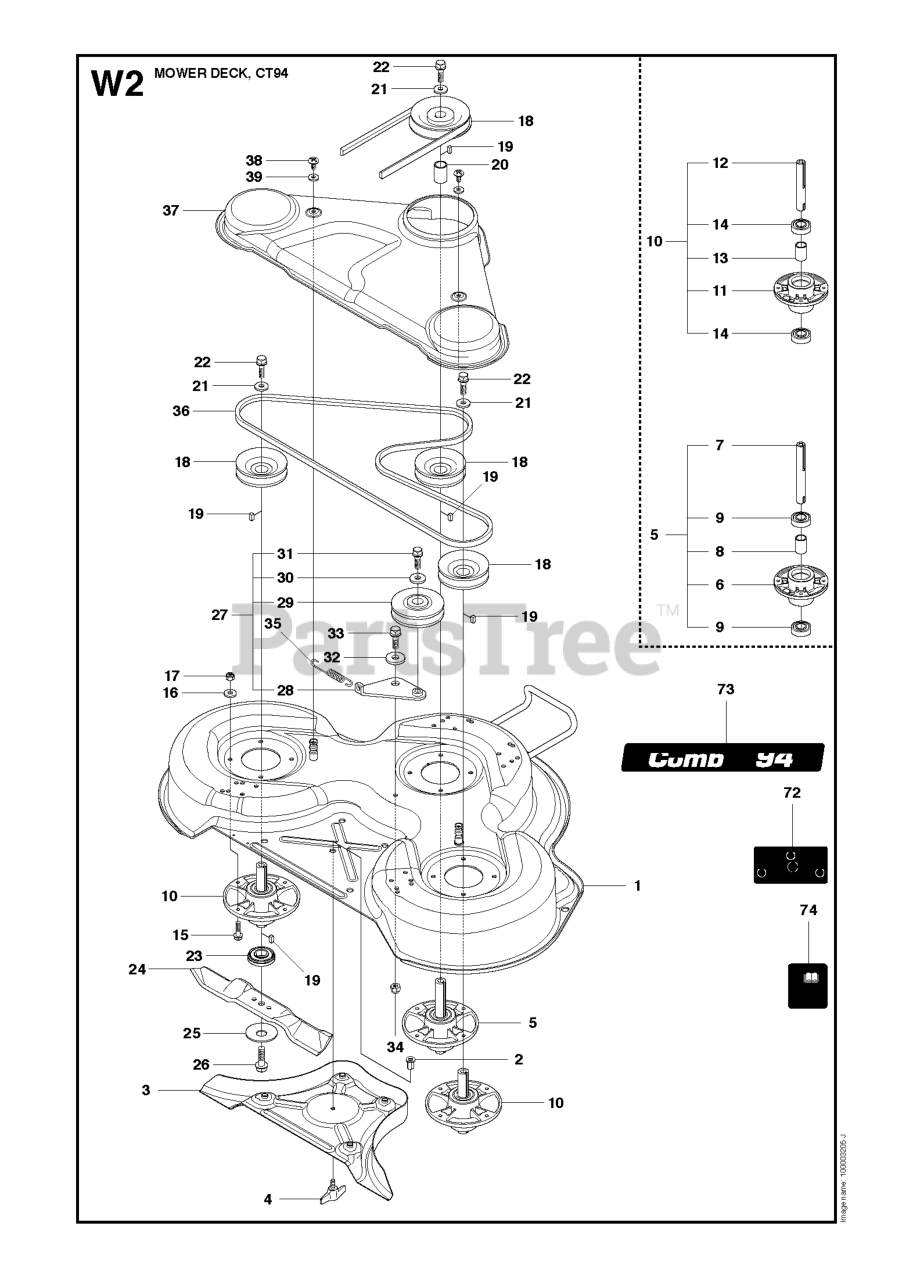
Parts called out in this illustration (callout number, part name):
1	DECK SHELL ASSY CT94 GREY
3	PLUG C93 & C94
6	BEARING HOUSING
9	BALL BEARING
11	BEARING HOUSING
14	BALL BEARING
16	WASHER BRB 8.4X17
17	LOCKNUT M8
27	BELT TENSIONER ASSY
28	BELT TENSIONING ARM
32	WASHER
34	LOCKNUT M8
37	BELT COVER C93 & C94 GREY
